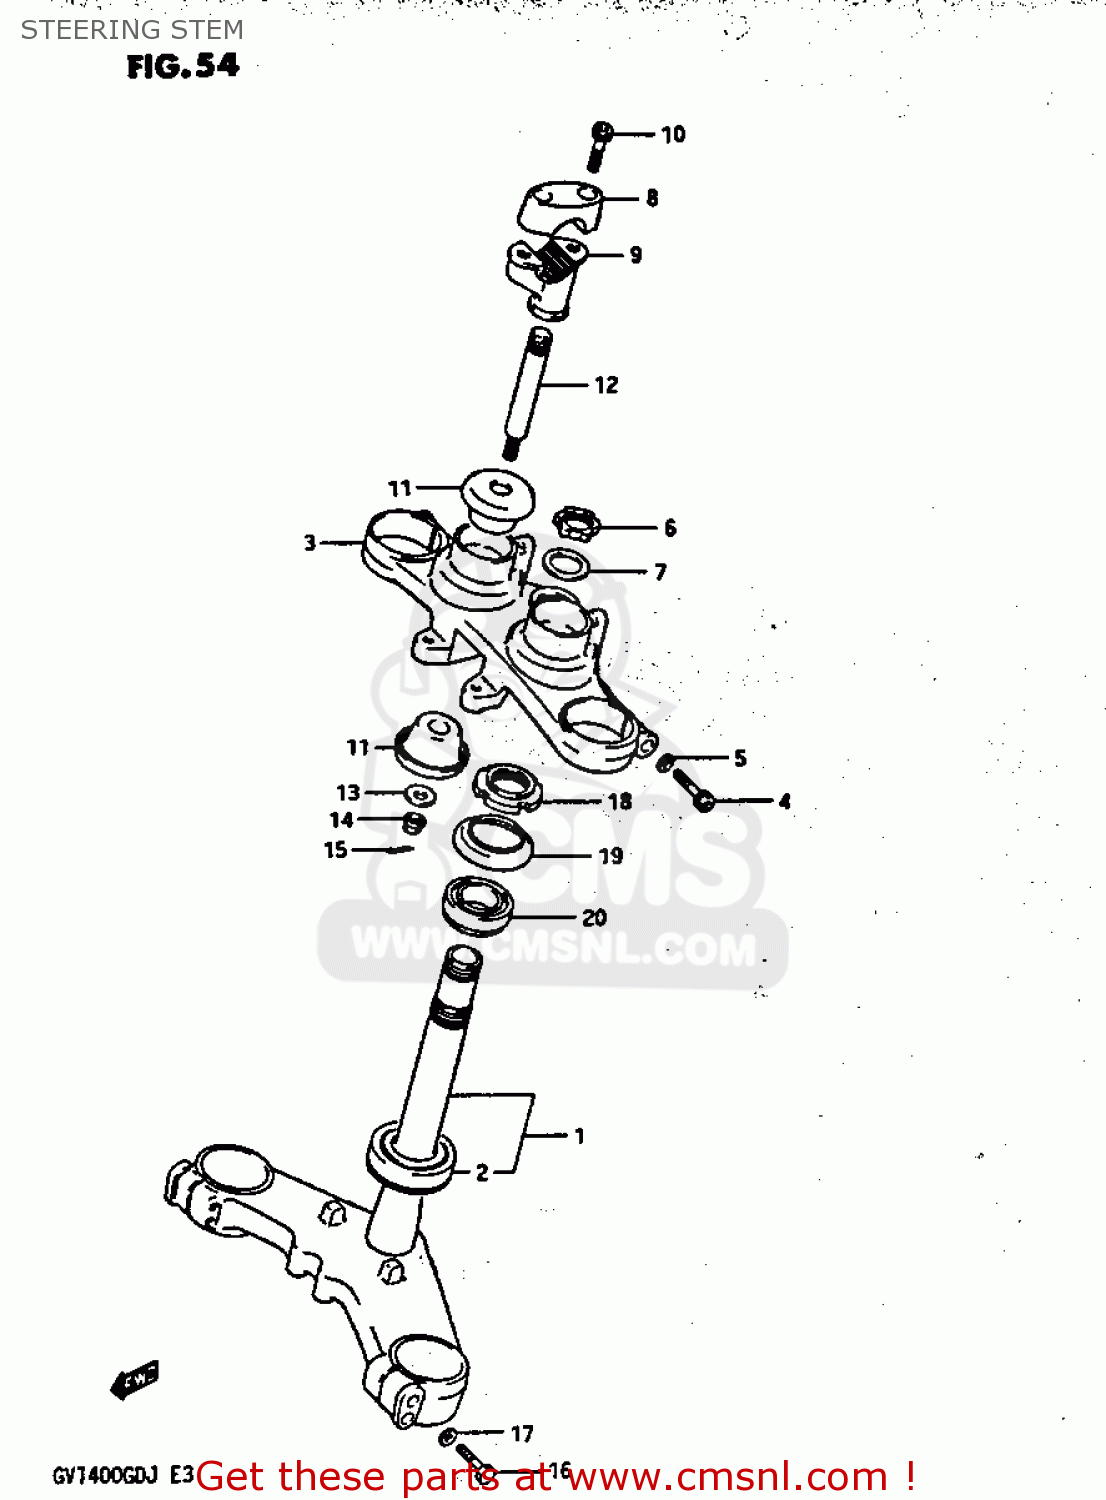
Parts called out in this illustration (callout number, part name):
1	STEM,STEERING
2	BEARING(30X55X17)
3	HEAD,STEERING STEM
4	BOLT
5	LOCK WASHER
6	NUT,STEERING STEM
7	WASHER,STEERING STEM
8	HOLDER,HANDLE,UPPER
9	HOLDER,HANDLEBAR
10	BOLT, FRONT LH
11	CUSHION
12	BOLT
13	WASHER,STEERING STEM
14	NUT
15	COTTER PIN
16	BOLT 8X40
17	LOCK WASHER
18	NUT,STEERING STEM(25X44X10)
19	SEAL,STEERING UPR DUST
20	TAPER,ROLLER BEARING
